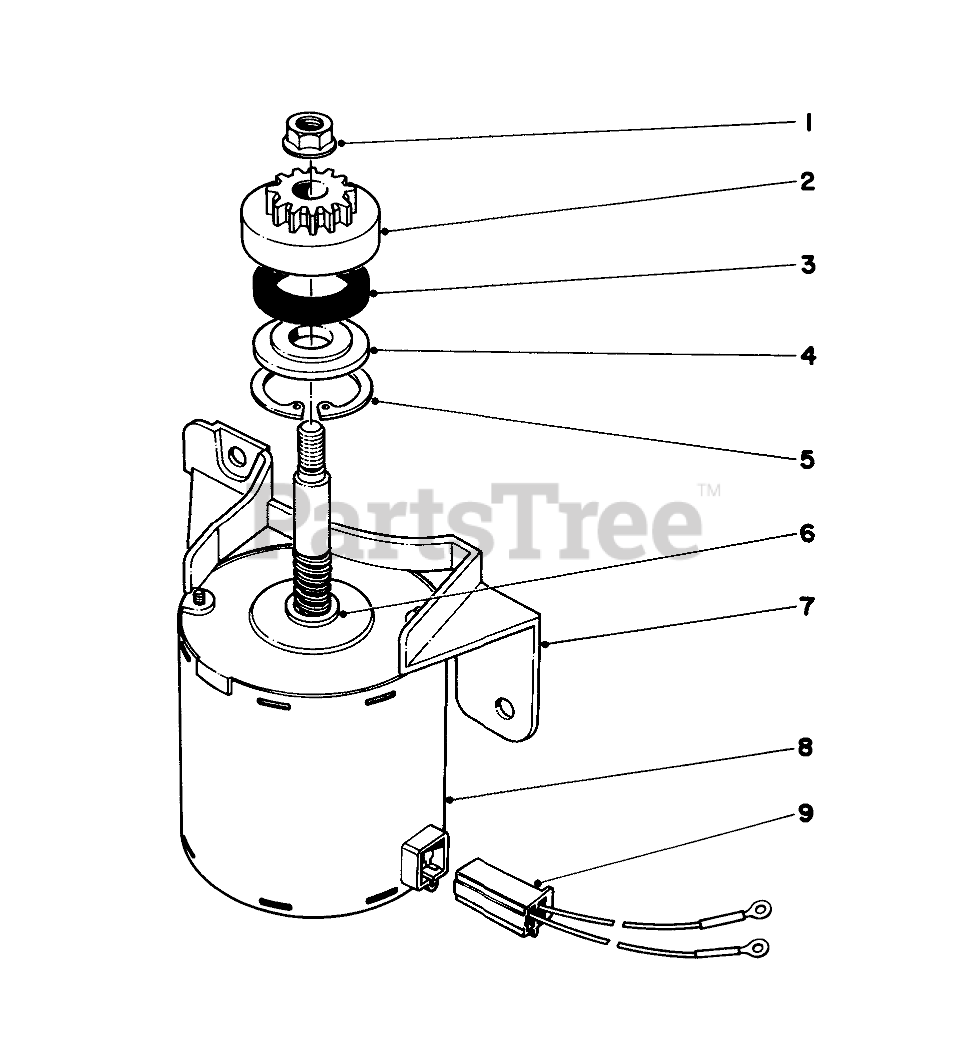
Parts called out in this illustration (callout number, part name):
1	NUT-HHF
2	Pinion Assembly (Incl. Ref. Nos. 3, 4 and 5)
3	RUBBER RING
4	Control Nut
5	Retaining Clip
6	Spacer
7	Mounting Bracket
8	Starter Motor
9	Terminal Assembly
